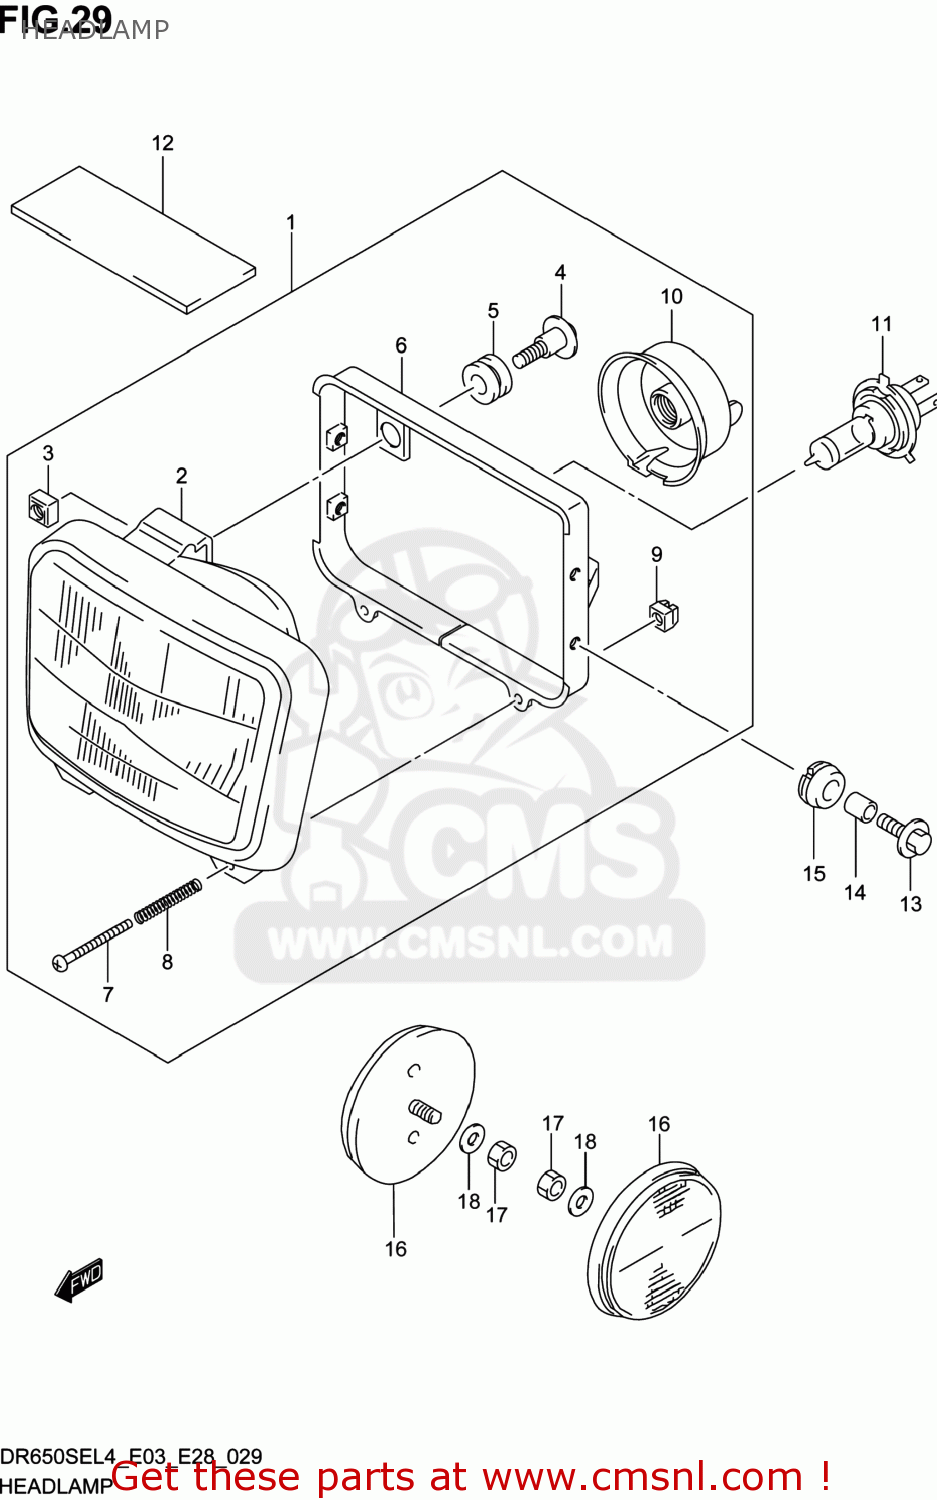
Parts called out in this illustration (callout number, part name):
1	HEADLAMP ASSY
2	UNIT ASSY
3	NUT
4	SCREW,MOUNTING
5	CUSHION
6	HOUSING
7	SCREW,ADJUSTING
8	SPRING,ADJUSTING
9	NUT,ADJUSTING
10	COVER,SOCKET
11	BULB(12V60/55W,H4)
12	PROTECTOR,WIRING HARNESS
13	BOLT(6X20)
14	SPACER(6.5X10X10)
15	CUSHION
16	REFLEX REFLECTOR ASSY,FR SIDE
17	NUT
18	WASHER,LOCK
